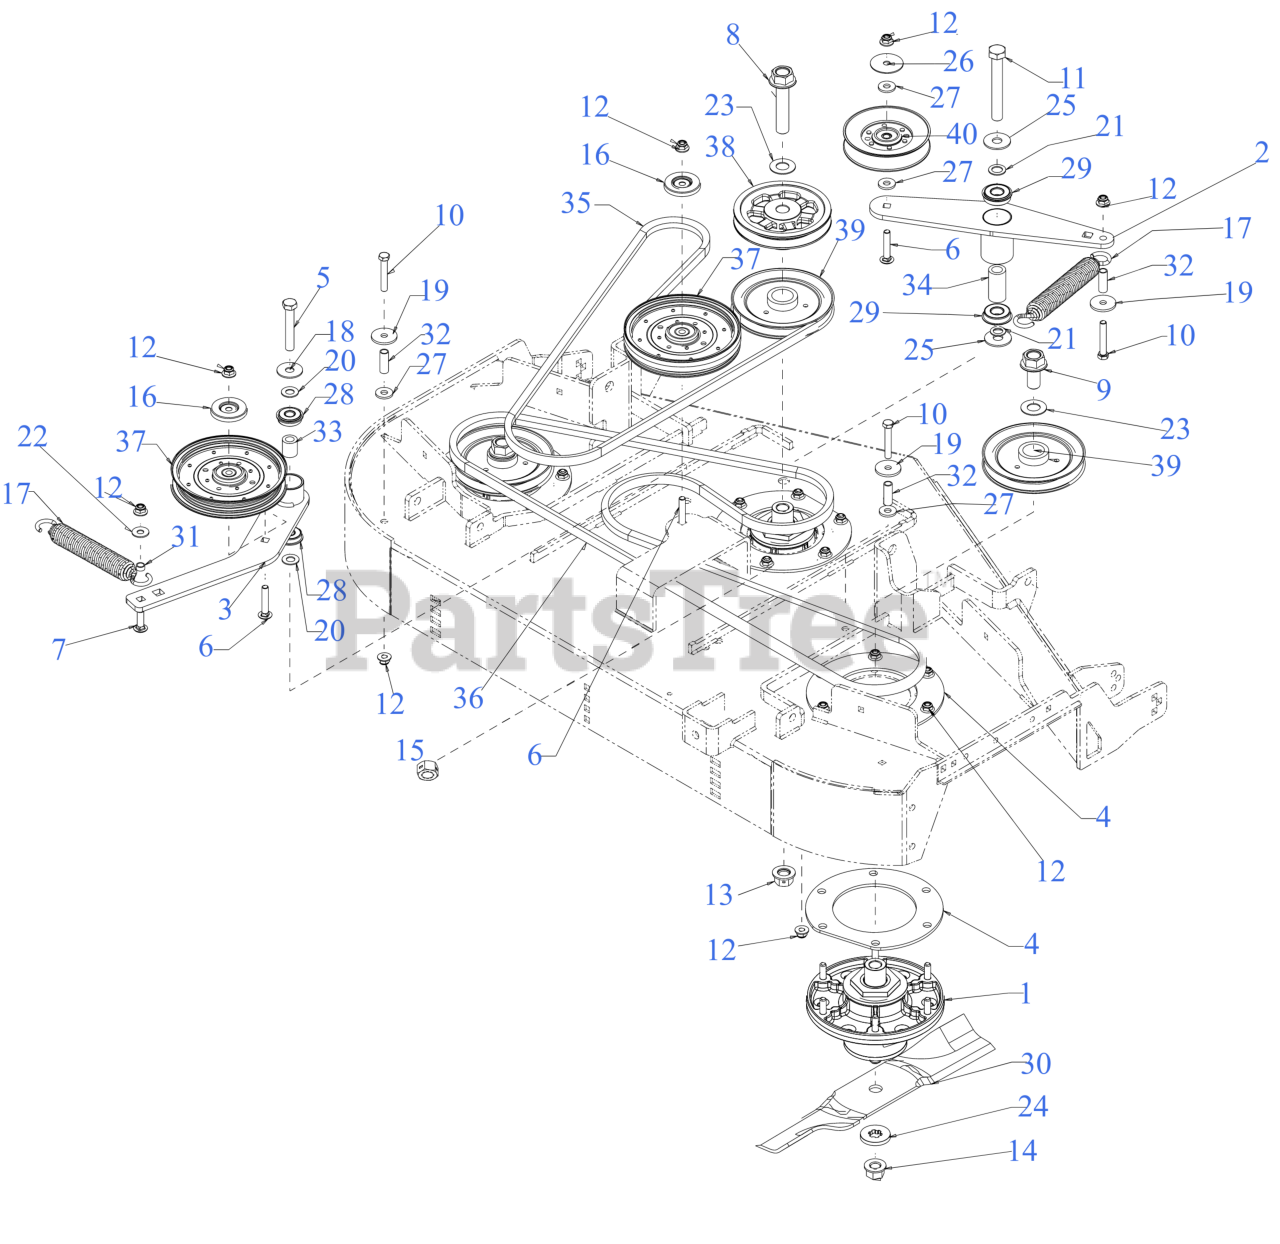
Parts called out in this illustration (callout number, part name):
1	SPINDLE ASSEMBLY
2	IDLER BRACKET
3	48" DECK IDLER BRACKET
4	SPINDLE SUPPORT BRACKET TOP/BTM
5	SCREW-HEX 1/2-13 x 3.00
6	CARRIAGE BOLT 3/8-16 x 2
7	CARRIAGE BOLT 3/8-16 X1.25 GR5
8	CAP SCREW-HHFLG 3/4-10 X 3.50 GR8
9	CAP SCREW-HHFLG 3/4-10 X 1.50 GR8
10	SCREW 3/8-16 x 2.25 GR5
11	SCREW 5/8-18X4.5 GR5
14	FLANGE NUT - 5/8-18 GDE 8
15	HEX NUT CTR LK 1/2-13
16	PULLEY CAP
17	SPRING 1.25" DIA x 8.5" LONG
18	WASHER .51 x 1.5 x .07
19	FLAT WASHER .390x1.500x.134
20	FLAT WASHER .510 x .995
21	FLAT WASHER
22	WASHER-.395 x 1.0 x .62
23	FLAT WASHER
24	FLAT WASHER - SPECIAL
25	FLAT WASHER 0.635xX1.755x0.110
25	THRUST WASHER .635x1.750x0.055
26	HUB CAP WASHER .406 x 1.92 x .060
27	FLAT WASHER .406ID X1.0 OD
28	ROLLER BEARING .5X1.37X.44
29	BALL BEARING W/RET
30	17" BLADE (HI LIFT)
30	Cub Cadet 48" HI LIFT BLADE SET
30	17" HI-LIFT BLADE 0.756 ID
30	LOW-LIFT 17" BLADE (48"DECK)
30	BLADE-HI LIFT 17.0
30	17" BLADE (MULCH)
33	SPACER 0.51 x 0.88 x 1.00
34	SPACER 0.63 x 1.00 x 2.01
35	BELT B SEC x 87.30
36	BELT B SEC X 109.9
37	IDLER PULLEY
38	DRIVE PULLEY
39	SPINDLE PULLEY 6"
40	IDLER PULLEY 5.06 OD
